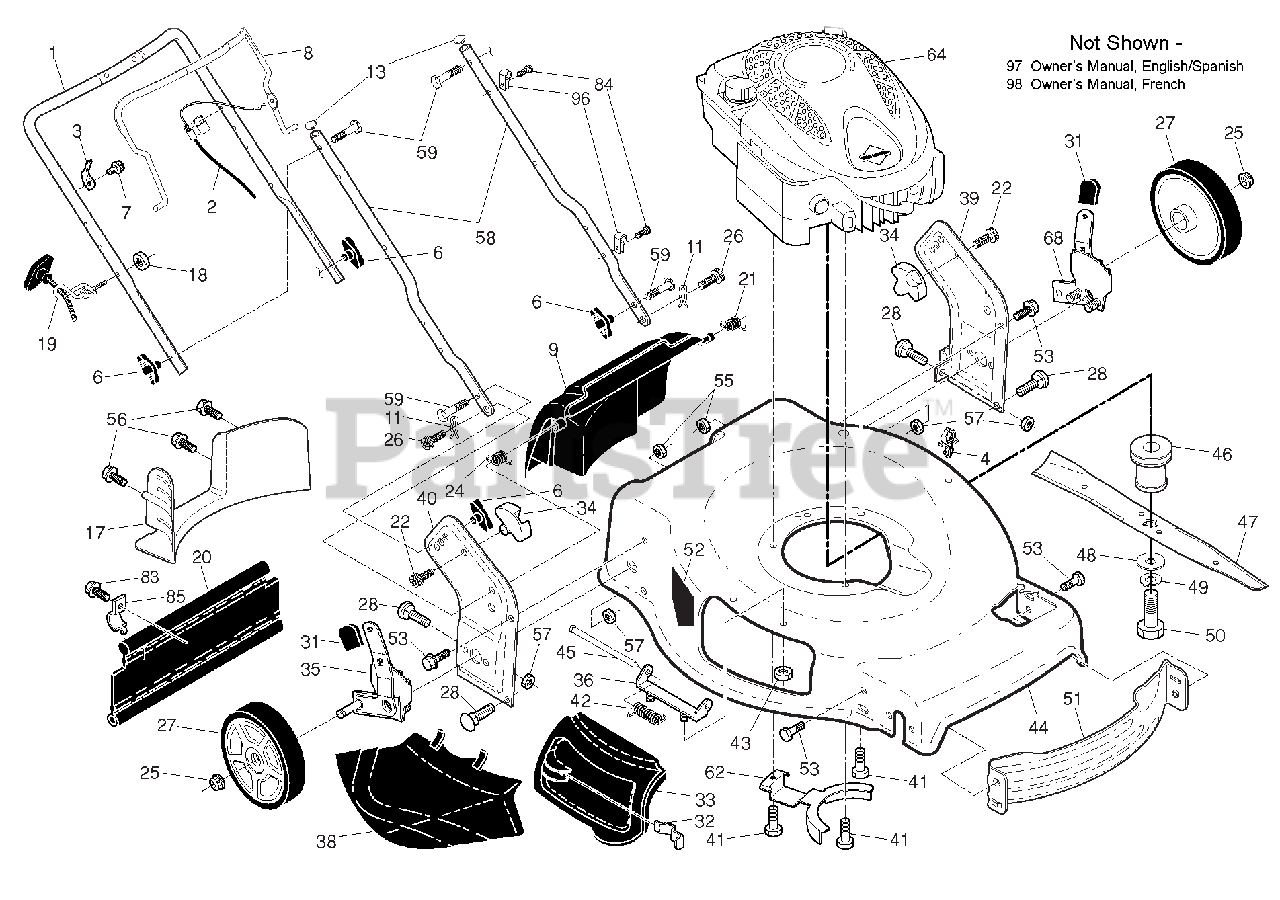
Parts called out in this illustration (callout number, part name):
1	UPPER HANDLE
2	CABLE, ENGINE ZONE CONTROL
3	UP-STOP BRACKET
4	CLIP.PUSH-IN.HINGED
6	Handle Knob
7	SCREW, HEX WASHER HEAD
8	CONTROL BAR
9	REAR DOOR ASSEMBLY
11	HAIRPIN, DOOR/HANDLE PIVOT
13	PLUG, HANDLE BAR
17	REAR BAFFLE
18	Nut, Hex
19	Rope Guide
20	REAR SKIRT
21	SPRING, REAR DOOR, LH, BLACK
22	SCREW, PANHEAD, TORX #20
24	SPRING, REAR DOOR, RH, GREY
25	Nut, Hex
26	SCREW, REAR DOOR/HANDLE PIVOT
27	WHEEL & TIRE ASSEMBLY, REAR
28	BOLT, CARRIAGE 5/16-18 X 5/8
31	Selector Knob
32	LATCH, MULCHER DOOR
33	MULCHER DOOR
34	BRACKET, GRASSBAG
35	KIT, WHEEL ADJUSTER, REAR, RH
36	Hinge Bracket Assembly
38	DISCHARGE DEFLECTOR
39	HANDLE BRACKET, LH
40	HANDLE BRACKET, RH
41	Screw, Hex Head, Threaded, Rol
42	Spring, Torsion
43	LOCKNUT, HEX 1/4-20
44	KIT, LAWN MOWER HOUSING
45	Rod, Hinge
46	BLADE ADAPTER / PULLEY
47	BLADE, 22"
48	Hardened Washer
49	Helical Lockwasher
50	Screw, Hex Head, Grade 8 3/8-2
51	FRONT BAFFLE
52	Danger Decal
53	BOLT.5/16-18HEX.WHS.HD.LCKSERR
55	LOCKNUT, HEX 1/4-20
56	Screw, Rear Baffle
57	NUT, HEX
58	BAR, LOWER HANDLE
59	Handle Bolt
62	BELT RETAINER
68	KIT, WHEEL ADJUST, REAR, LH
84	FASTENER, PUSH
85	MOUNTING BRACKET, REAR SKIRT
96	Clip, Cable
97	OWNER'S MANUAL ENGLISH/SPANISH
98	OWNER'S MANUAL FRENCH
